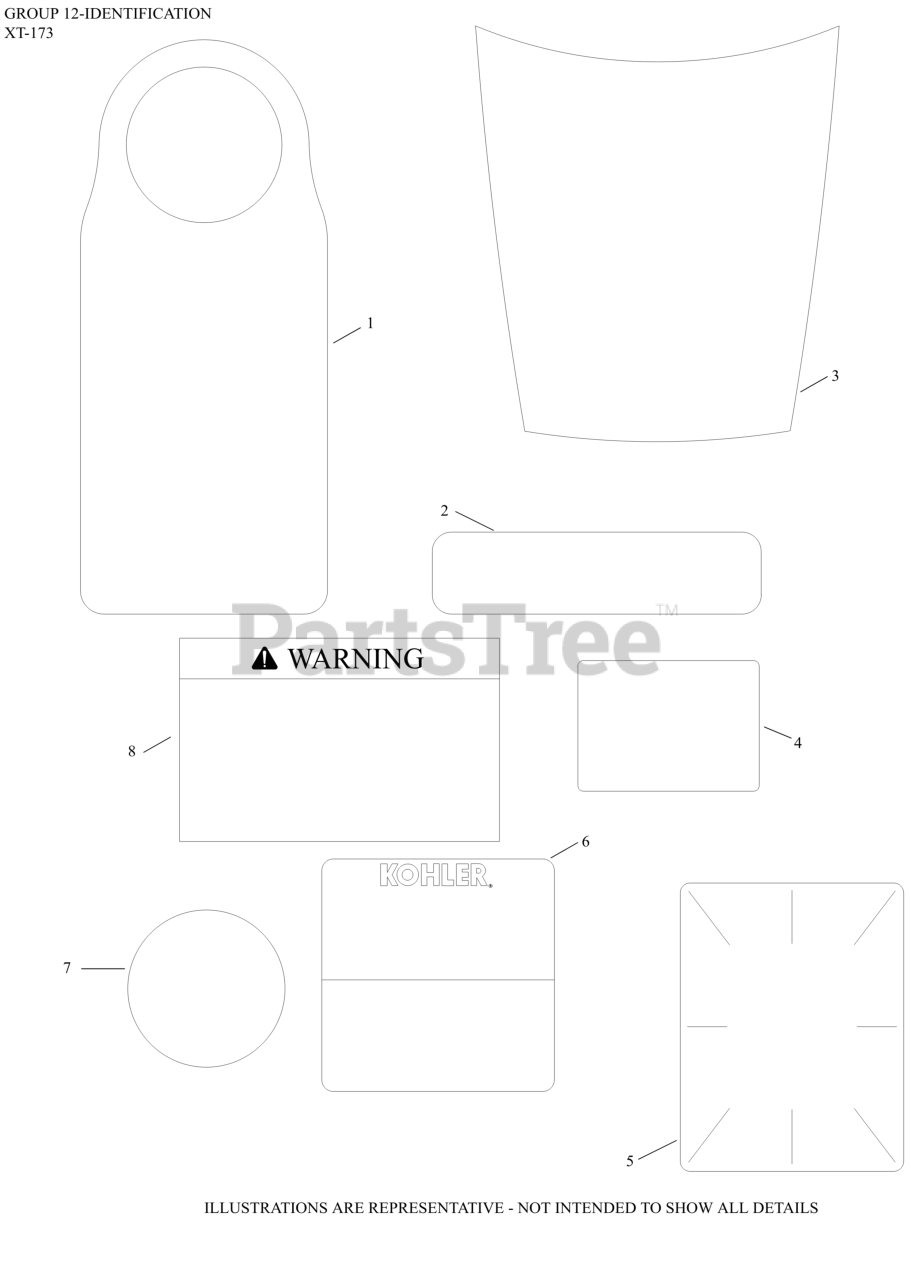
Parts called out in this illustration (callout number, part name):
1	TAG, MAINTENANCE HANG (#1445003-S)
4	DECAL, PRIMER
6	NAMEPLATE, SERVICE
8	DECAL, WARNING - USE 14 113 57-S
